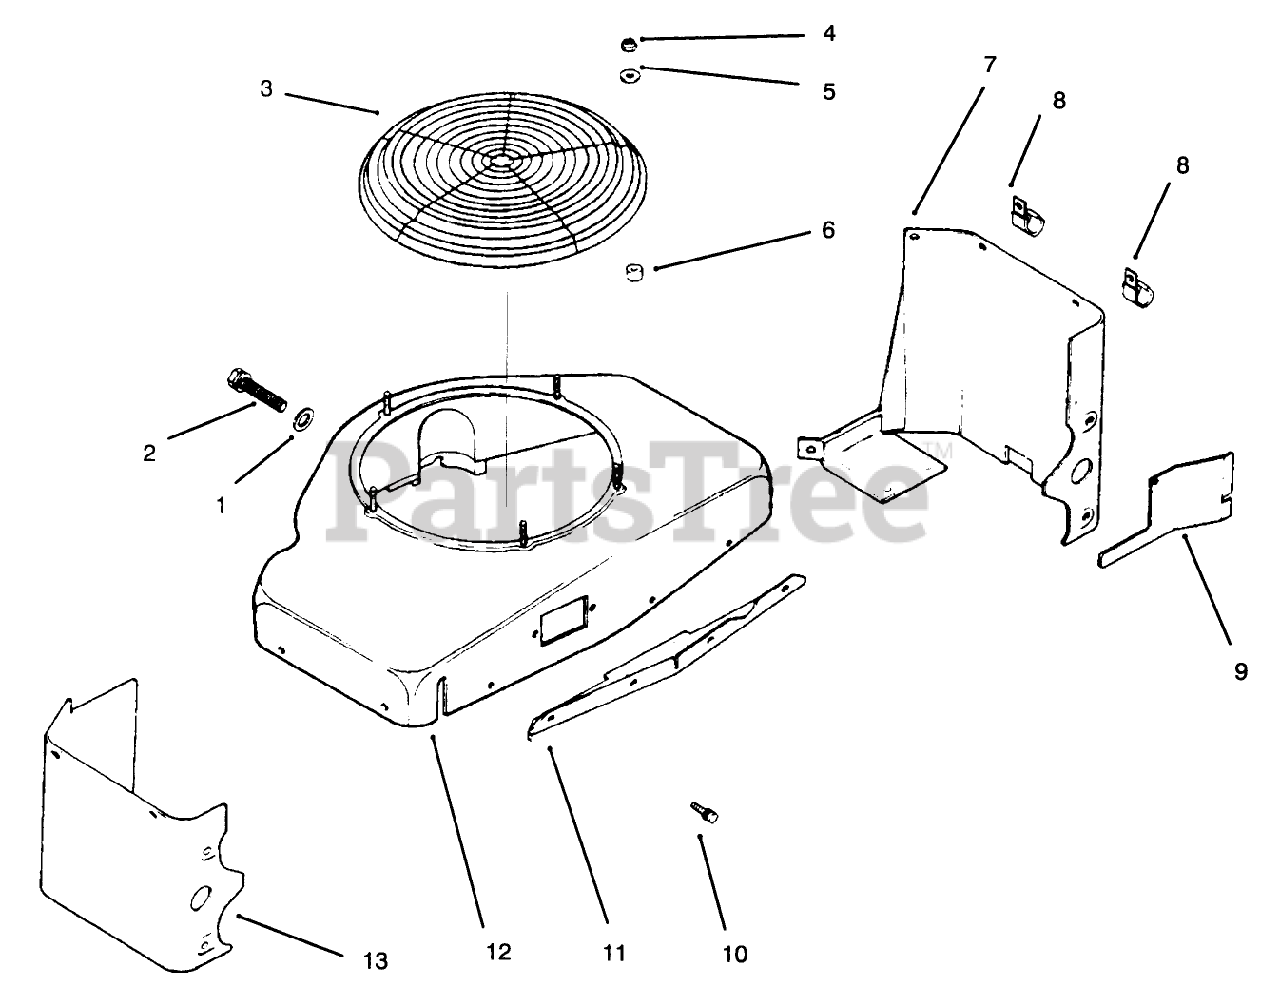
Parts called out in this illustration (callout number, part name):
1	Washer
2	Screw-Self Tap
3	Guard-Grass Screen
4	Nut-Lock
5	Washer
6	Spacer
7	Baffle-Cylinder Head
8	Clamp
9	Baffle-Cylinder Head
10	Screw
11	Support-Upper Housing
12	Kit-Blower Housing (Incl. Ref. #1, 2 & 11)
13	Baffle-Cylinder Head
